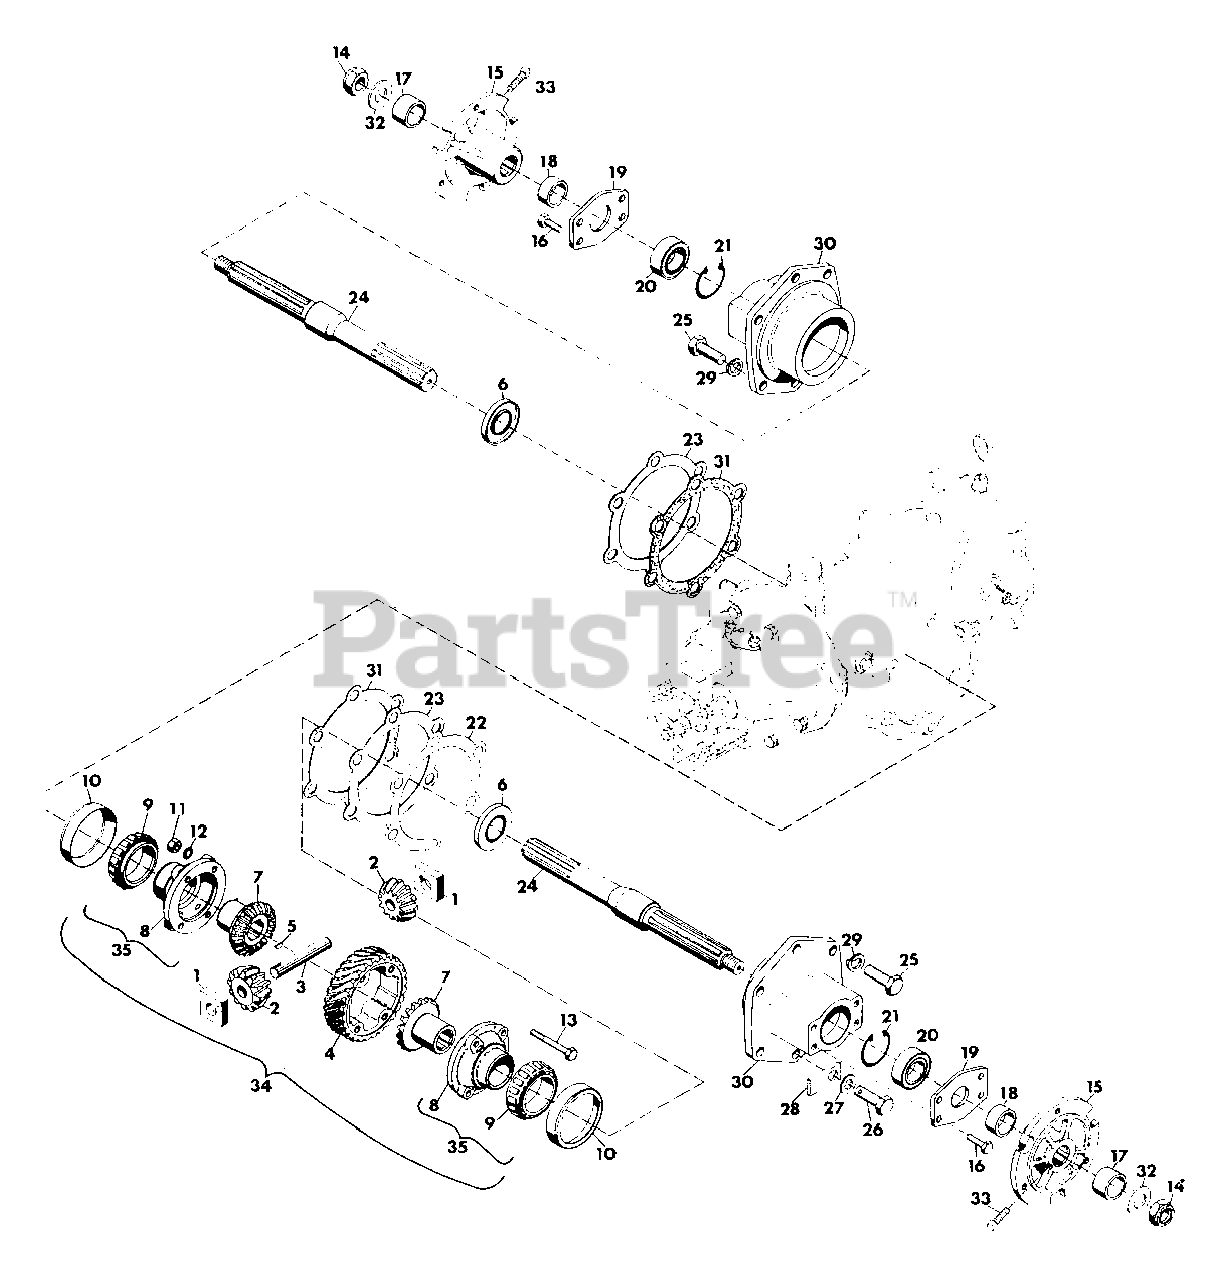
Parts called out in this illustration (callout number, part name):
1	Block, Drive
2	Gear, Spider Bevel
3	Pin, Spider Pinion
4	Gear, 6 Start Worm
5	Key, Woodruff .125x.375 Hard
6	Seal, Oil 1.188x2.00x.250
7	Gear, Differential Bevel
8	Housing, Differential
9	Cone, Roller Bearing
10	Cup, Roller Bearing
11	Nut, Hex 5/16-24
12	Washer, Lock 5/16 Int. Tooth
13	Bolt, Hex 5/16-24x2.75
14	Nut, Hex 3/4-10 Light Thin
15	Hub, Wheel
16	Bolt, Hex 3/8-16x-.750
17	Spacer
18	Spacer
19	Plate, End
20	Bearing, Ball 1.000x2.000x.562
21	Ring, Retaining 2.000 Bore
22	Shim, Axle Housing .020
23	Shim, Axle Housing .005
24	Axle, Straight
25	Bolt,Hex 1/2-13x1
26	Bolt, Hex 1/2-13x1 Nylon Insert
27	Washer, Flat .531x1.062x.095
28	Washer, Oil Drain
29	Washer, Lock SP
30	Housing, Axle
31	Gasket, Axle Housing
32	Washer, Flat .812x1.469x.134
33	Screw, Set 7/16-14x1.00
34	Assembly, Diff. Std. 6 Lead
35	Assembly, Differential Housing
